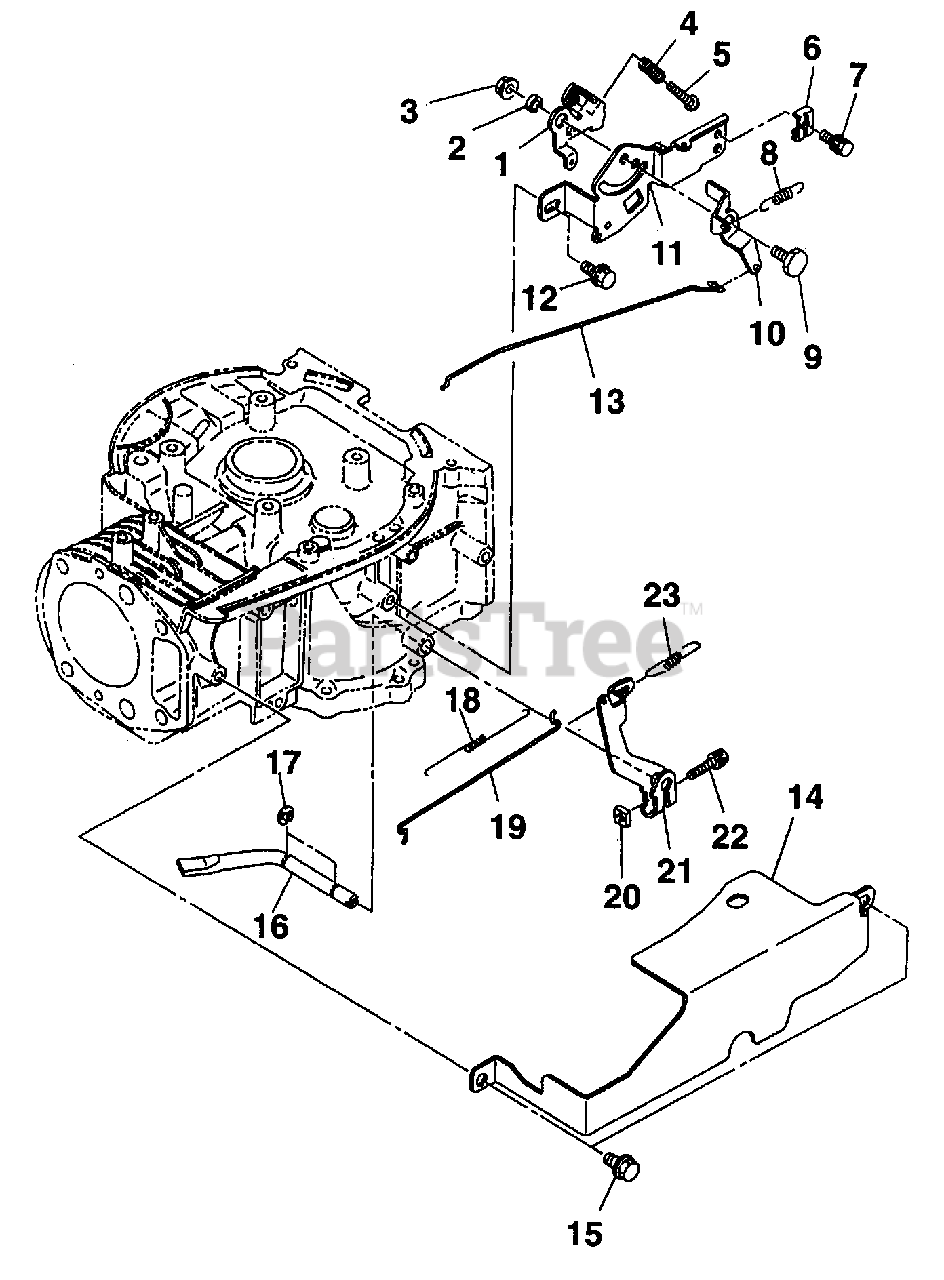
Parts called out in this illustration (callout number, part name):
1	LEVER, Speed Control
3	NUT, Flange
4	SPRING, Adjust
5	SCREW, Pan Head
7	BOLT AND WASHER
8	SPRING, Return
9	PIVOT, Link
10	LEVER, Choke
12	BOLT, Flange
13	ROD, Choke
14	GUARD, Side
15	BOLT, Flange
16	SHAFT, Governor
18	SPRING, Rod
19	ROD, Governor
20	NUT
21	LEVER, Governor
22	BOLT AND WASHER
23	SPRING, Governor
